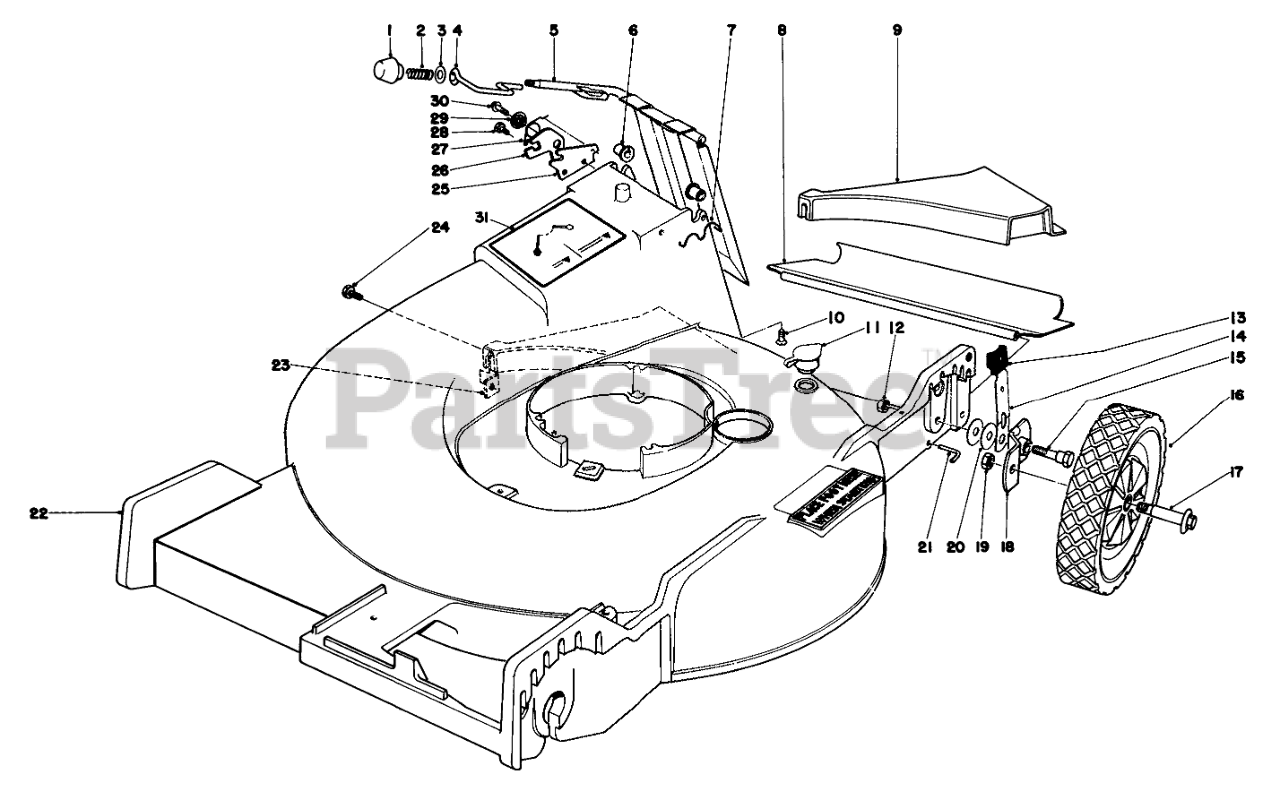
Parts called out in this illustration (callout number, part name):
2	COMPRESSION SPRING
3	WASHER
4	DOOR LATCH
5	Door Handle
6	BUSHING-NYLON
7	Door Retainer
8	REAR SAFETY SHIELD
9	REAR INSERT
10	SCREW-HH
11	WASHOUT PLUG
12	Nut
13	KNOB-ARM
14	SPRING ARM ASM
15	PIVOT SCREW
16	WHEEL TIRE ASM 8 IN
17	BOLT-WHEEL
18	PIVOT ARM ASM A
19	Nut
20	WASHER-PIVOT
21	ROD-SHIELD
22	Housing
23	SPECIAL NUT
24	SCREW THD 1/4 20 5/8
25	DOOR LATCH PLATE
26	Latch Safety
27	TORSION SPRING
28	SCREW-HWH
29	Latch Spacer
30	Screw
31	Decal-Caution (French & Dutch)
